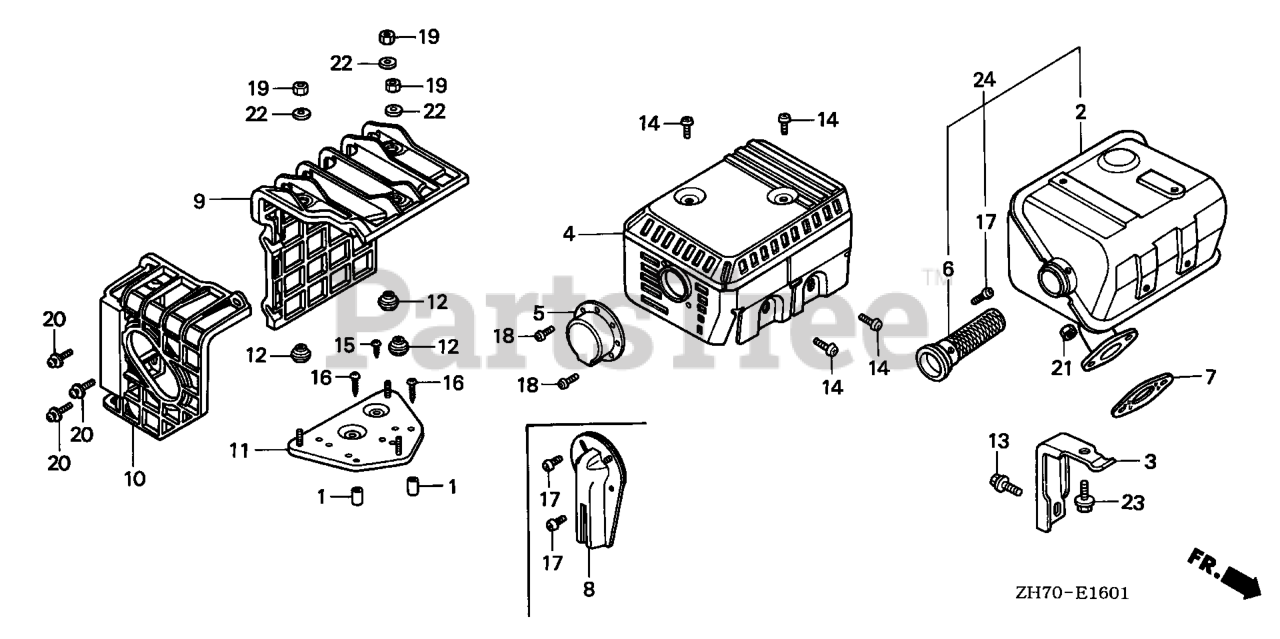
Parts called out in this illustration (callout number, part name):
2	MUFFLER (SILENT)
3	STAY, MUFFLER
4	PROTECTOR, MUFFLER (SILENT)
5	CAP, MUFFLER
6	ARRESTER, SPARK (SILENT)
7	GASKET, MUFFLER
13	BOLT, FLANGE (6X13)
14	SCREW, TAPPING (5X8)
17	SCREW, TAPPING (4X6)
18	SCREW, TAPPING (4X8)
18	SCREW, TAPPING (4X6) (TO INSTALL OPTIONAL SPARK ARRESTER)
21	NUT, HEX. (8MM)
23	BOLT, FLANGE (6X12) Use up to Engine SN 1543277.
